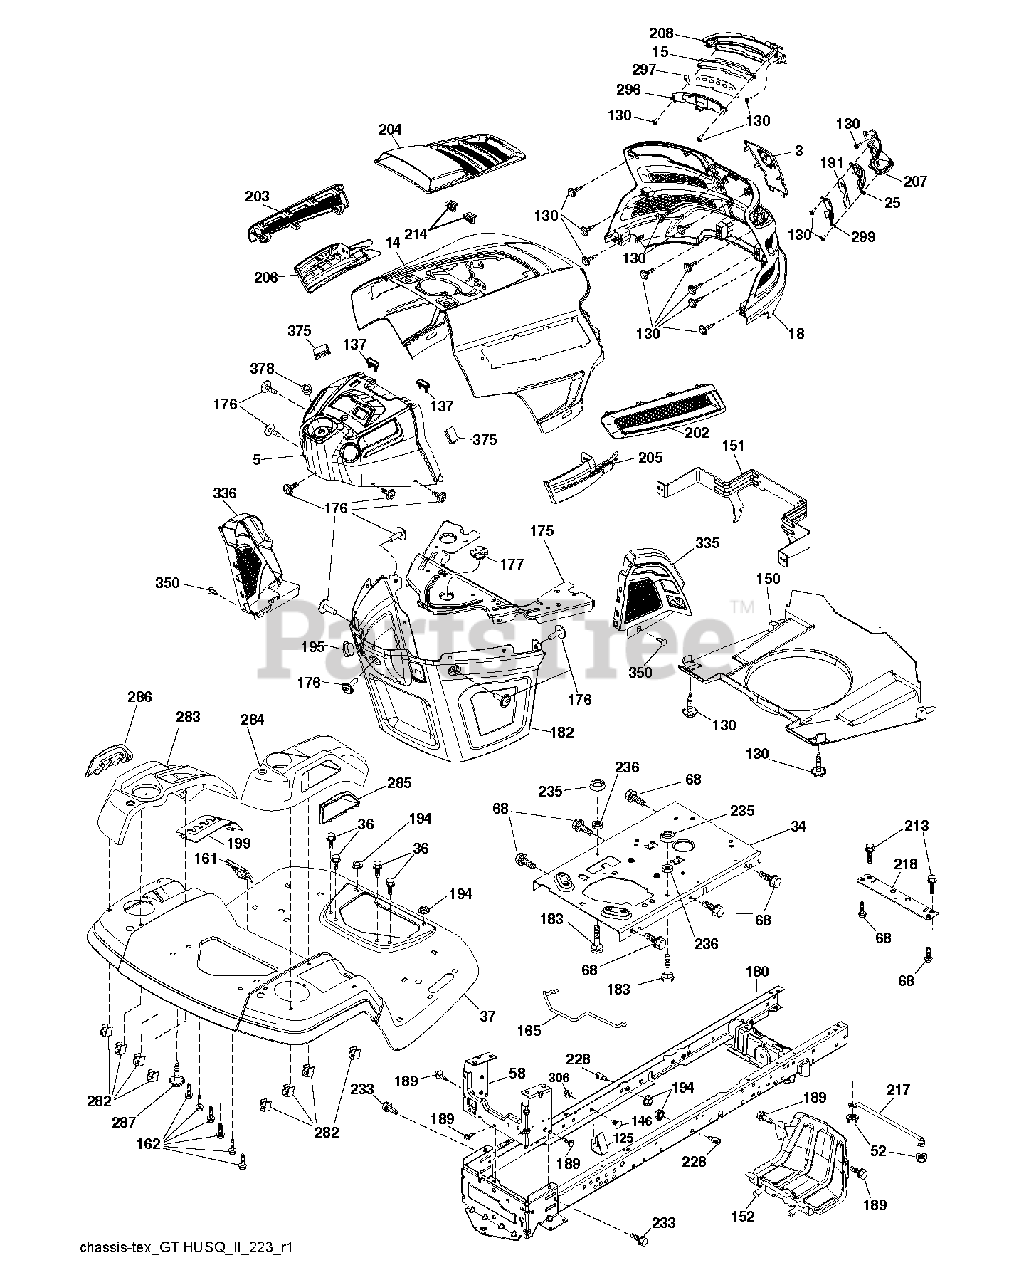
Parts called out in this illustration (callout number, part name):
3	APPLIQUE.SUBASM.GT.HUSQ.II
5	DASHBOARD.TEX.GT2.UPPER.S.PTO
14	HOOD.ASM.HUSQVARNA.GT.TEX.ORAN
15	LED LIGHT.LH
18	GRILLE SUBASM.GT.II.LOW.HDLGHT
25	LENS.RH
34	PLATE.ENGINE.WELDED.CHASSIS
36	SCREW 5/16"
37	FENDER.TLT.FS.W/CPH/FW/RSF.668
52	LOCKNUT
58	DRAWBAR UPPER 2PC SMALL FENDER
68	SCR 5/16-18 X 1/2 SELFTAP ZN
125	CLIP.FUEL.LINE
130	SCREW.#10 X 0.750.BOS
137	BUMPER DASH
146	BOLT.RDHD.SHT.SQNK.3/8-16X5/8
150	AIR.DUCT.GTV.BLACK
151	BRACKET.PIVOT.HOOD.GT.HUSQ.II
152	SHIELD.BROWNING.PNT.GT.V2
161	WINDOW.FUEL.LT.HUSQ.TEX.498
162	SCREW.HI-LO.CONSOLE
165	SUPPORT.TANK.REAR.W/TEX
175	Crossmember Plate
176	SCREW.#10-24X5/8.RN.QU
177	BUSHING STEERING
180	CHASS.WLDMNT.TL.12GA/2P.48/54
182	DASH.LOWER.COMMON.12V.ADAPTOR
183	BOLT.5/16-18X1-1/4 FULL THD
189	SCREW
191	INSERT INFLECT.RH
194	NUT LOCK HEX FLANGE 5/16-18
195	PLUG.HOLE.DASH.LOWER.12V.BLK
199	PLATE.DECK.LIFT.HUSQ.LT
202	VENT.SIDE.RH.GT.HUSQ.II.
203	VENT.SIDE.LH.GT.HUSQ.II.498
204	VENT.TOP.HUSQ.GT2
205	SIDE.TRIM.RH.GT.HUSQ.II
206	SIDE.TRIM.LH.GT.HUSQ.II.GRAY
207	BEZEL GT2 LED RH W/ LOWER.ATT
208	BEZEL GT2 LED LH W/ LOWER ATT
213	BOLT
214	CLIP.RETAINER.TINNER.
217	ROD.PIVOT.HOOD
218	X-PIECE.HOOD.STOP.NON/
228	STUD.FASTNER.W/ANTI-ROTATE
233	BOLT.SHOULDER
235	SPACER FENDER
236	NUT.CENTERLOCK.5/16-
282	CLIP.RETAINER.CONSOLE.LT.HUSQ
283	CONSOLE.DECK.LIFT.R.SDFL.HUSQ
284	CONCOLE.CNTRL.PDL.HUSQ.LT.498
285	CONSOLE INSERT RH
286	CONSOLE.INSRT.LH.HUSQ.LT.BLACK
287	SCREW 1/4X20
296	LED LIGHT.LH
297	INSERT REFECT LH
299	LED LIGHT.RH
306	NUT LOCK FLG 3/8-16 UNC
335	COVER.LOWER.DASH.RH.BLACK
336	COVER-LH.LOWER.DASH.GT2.BLACK
350	CLIP.X-MAS.TREE
375	BUMPER CLIP-ON. DASH 1"
378	BUSHING FLANGE; PLASTIC
